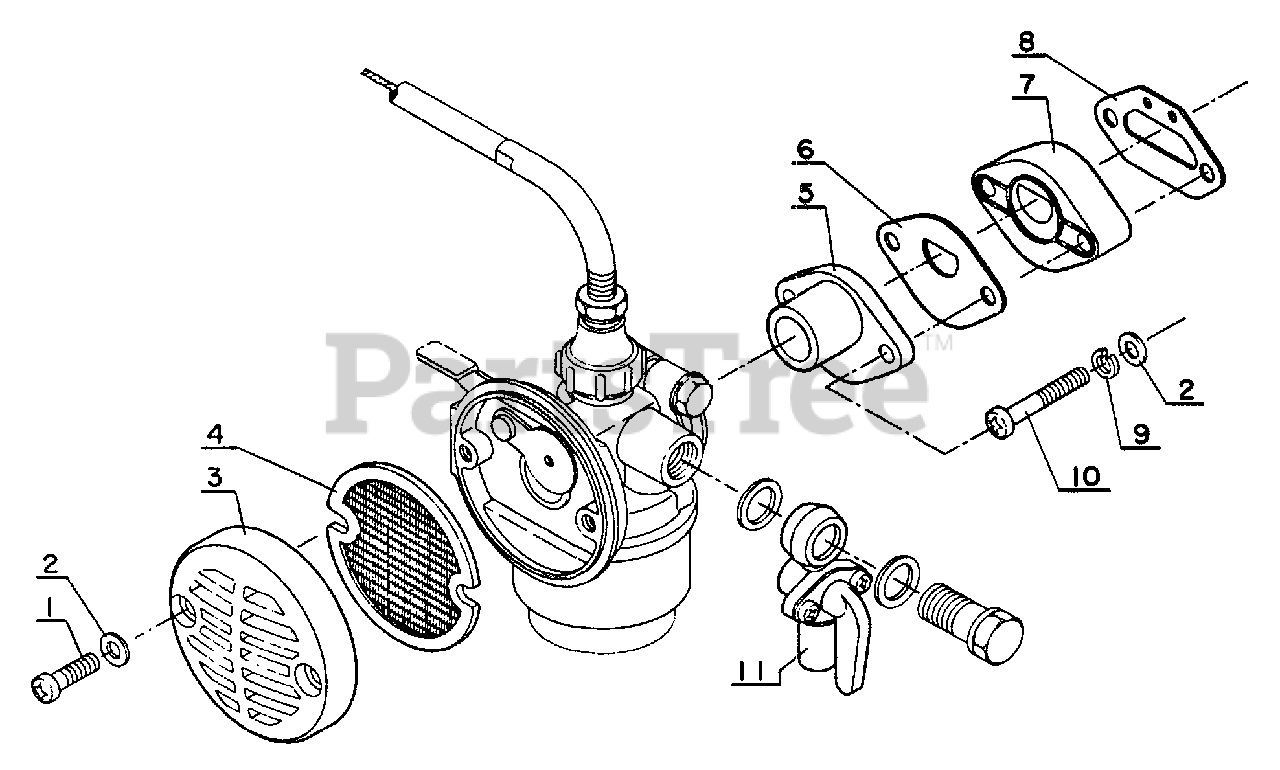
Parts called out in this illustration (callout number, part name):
1	SCREW - 4X12
2	WASHER - 4
3	COVER, AIR FILTER
4	FILTER, AIR
5	ADAPTOR, INTAKE
6	GASKET, INTAKE
7	INSULATOR, INTAKE
8	GASKET, INTAKE
9	LOCKWASHER - 4
10	SCREW - 4X25
11	FUEL VALVE ASSY
